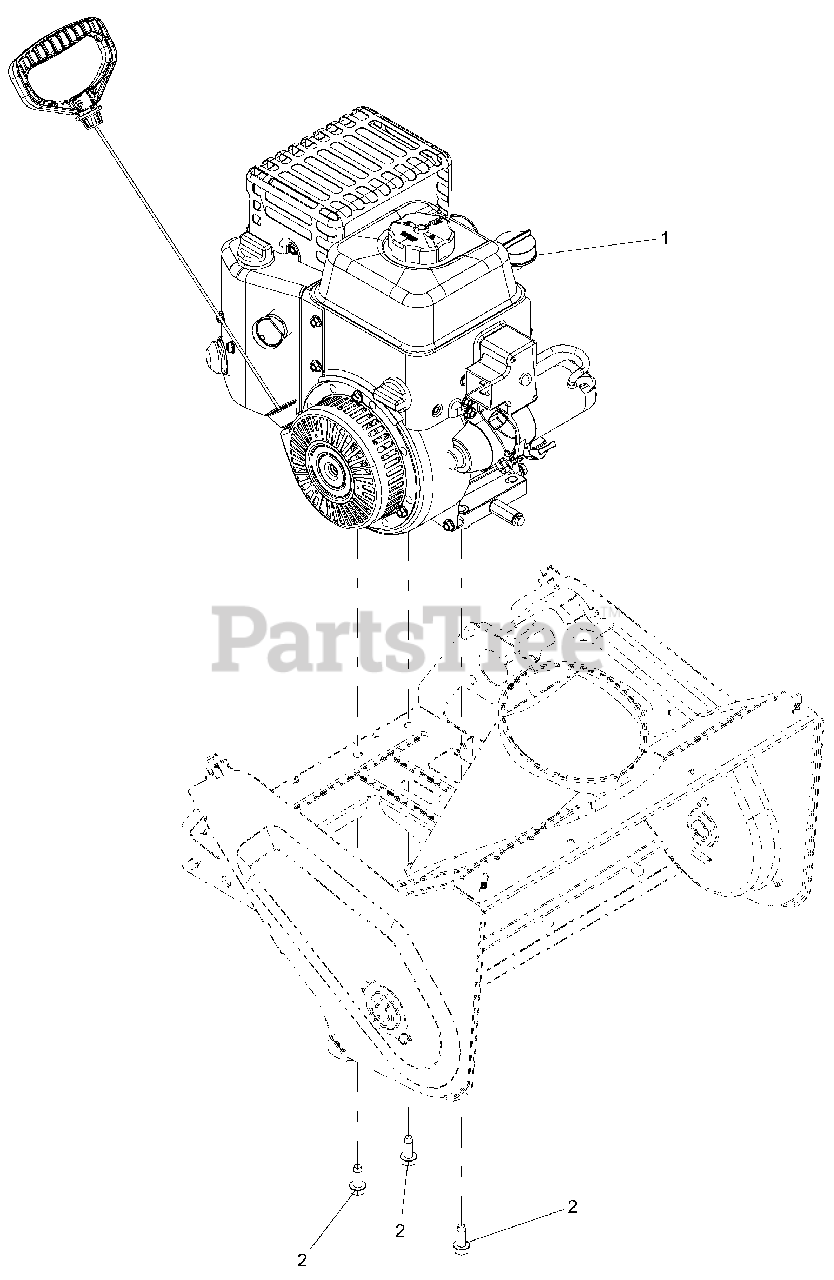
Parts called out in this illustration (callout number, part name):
1	ENGINE, ARIENS AX208 ES
1	PLUG, SPARK
1	CAP, FUEL TANK BLACK
1	KEY, TURN LCT (2/PACKAGE)
2	@SCR-TAP .38-16X1.00 HWH TR YZ
